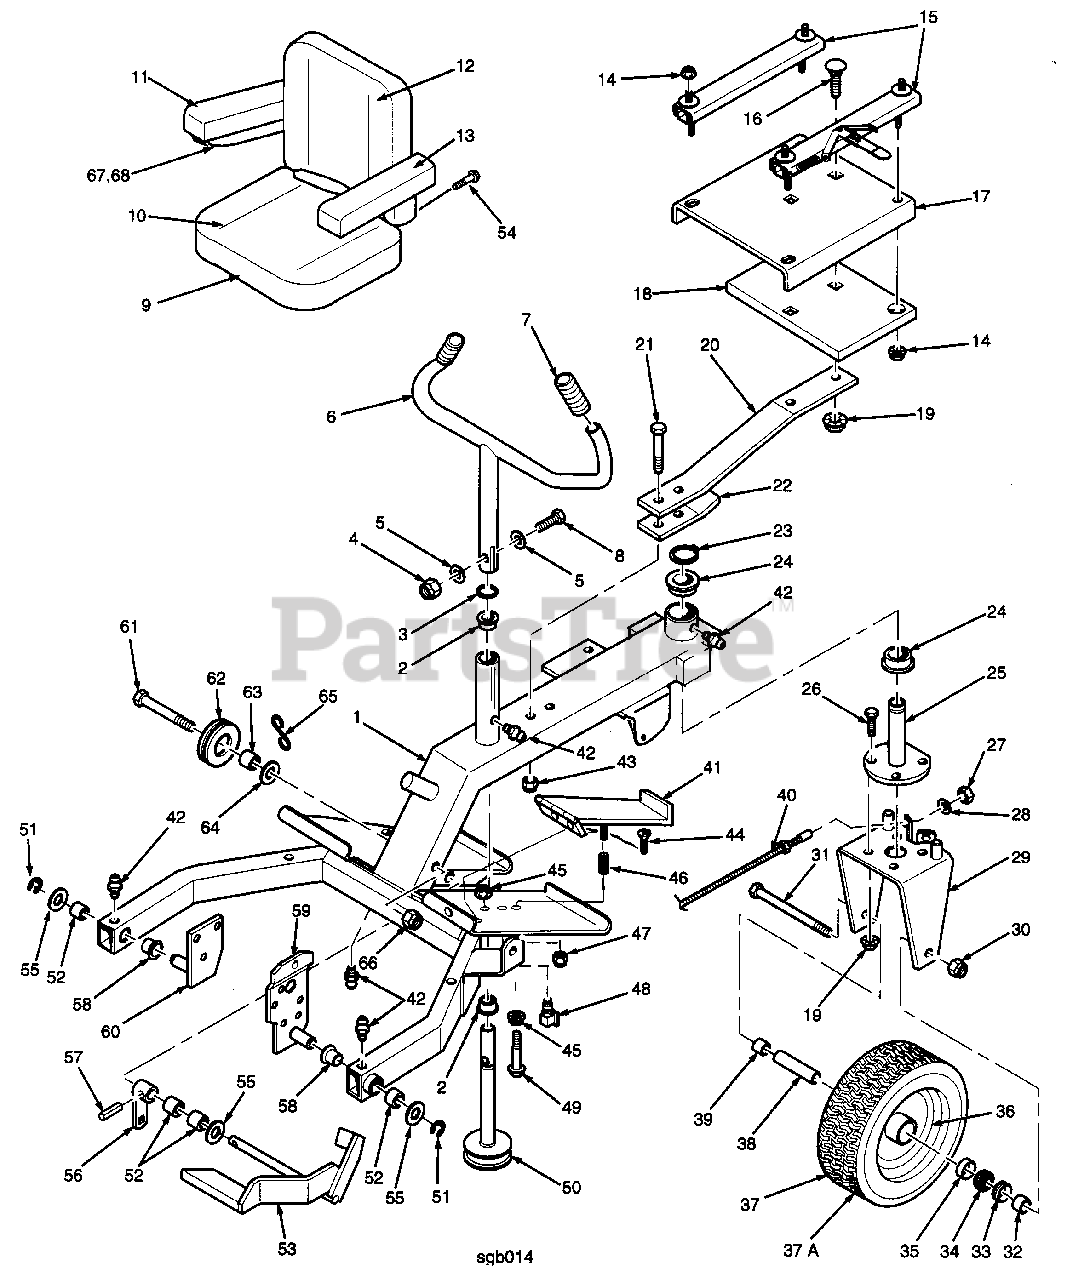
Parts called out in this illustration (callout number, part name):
1	STEERING FRAME(INCLUDES BSHGS AND FITTINGS)
2	BRONZE BUSHING, 7/8 ID X 1.0 FLANGED
3	RETAINING RING, 7/8 EXTERNAL
4	HEX NUT, ELASTIC STOP 5/16-18
5	FLAT WASHER, 5/16(3/8 X 7/8 X 13 GA.)
6	STEERING HANDLE(INCLUDES ITEM 7)
7	GRIP
8	BOLT, HEX HD., 5/16-18 X 1-3/4"
9	SEAT ASSY.(INCLUDES ITEMS 10 THRU 15, 67&68)
10	CUSHION ASSEMBLY
11	ARM PAD - R.H.
12	SEAT BACK CUSHION
13	ARM PAD L.H.
14	SERR. FL. HH. NUT, 5/16-18
15	SEAT ADJUSTER TRACK
16	BOLT, RDHD CARR. 3/8-16 X 1-1/2(52" & 61")
16	BOLT, RDHD CARR. 3/8-16 X 2.0"(72")
17	SEAT PLATE
18	BALLAST, SEAT MOUNT(72" CUTTER DECK ONLY)
19	SERR FL. HEX NUT, 3/8-16
20	SEAT SPRING
21	BOLT, HEX HD., 7-16-14 X 3-1/2
22	REINFORCEMENT, SEAT SPRING
23	RETAINING RING, 1-1/8" EXTERNAL
24	BUSHING, OILITE - 1-1/8 ID X 1.0 FLANGED
25	REAR WHEEL PIVOT
26	BOLT, HEX HD., 3/8-16 X 1-1/4
28	LOCK WASHER, 3/8 INTERNAL TOOTH
29	REAR WHEEL YOKE
30	HEX ELASTIC STOP NUT, 5/8-11
31	BOLT, HEX HD. 5/8-11 X 9"
32	SPACER, REAR WHEEL, SHORT
33	SEAL, GREASE
34	BEARING CONE
35	BEARING CUP
36	RIM ONLY
37	REAR WHEEL ASSY.(INCLUDES ITEMS 33-36, 37A)
37A	TIRE ONLY
38	SLEEVE, REAR WHEEL
39	SPACER, REAR WHEEL
40	CABLE, STEERING(INCLUDES HARDWARE)
41	PEDAL, FOOT SAFETY SWITCH
42	GREASE FITTING
43	HEX ELASTIC STP NUT, 7/16-14
44	SCREW, PHILLIPS FLAT HD #10-32 X 3/4"
45	SERR. FL. HEX NUT, 1/4-20
46	SPRING, FOOT SAFETY SWITCH
47	HEX NUT, ELASTIC STOP LOCK, 1/4-20
48	SWITCH, FOOT SAFETY
49	BOLT, HEX HD., 1/4-20 X 1-3/4
50	STEERING SHAFT
51	RETAINING RING 3/4 EXT. "E"
52	BUSHING, OILLUBE - 3/4 ID X 1.0
53	FOOT PEDAL
54	SCREW W/WASHER, 1/4-20 X .75
55	FLAT WASHER, 3/4 X 1-1/4 X 16 GA.
56	FOOT PEDAL ARM
57	PIN, DRIVE LOCK 3/16 X 1-1/4"
58	BUSHING, OILLUBE - 3/4 X .50 FLANGED
59	SULKY MTG. BRKT. L.H.
60	SULKY MTG. BRKT. R.H.
61	BOLT, HEX HD., 1/2-13 X 5-1/2"
62	PULLEY, WINCH CABLE
63	BUSHING, OILLUBE - 1/2 ID X .56
64	FLAT WASHER, 1/2(.562 X 1.375 X .109)
65	RETAINER, WINCH CABLE
66	HEX ELASTIC STOP NUT, 1/2-13
67	ARM REST BRACKET, LEFT HAND
68	ARM REST BRACKET, RIGHT HAND
